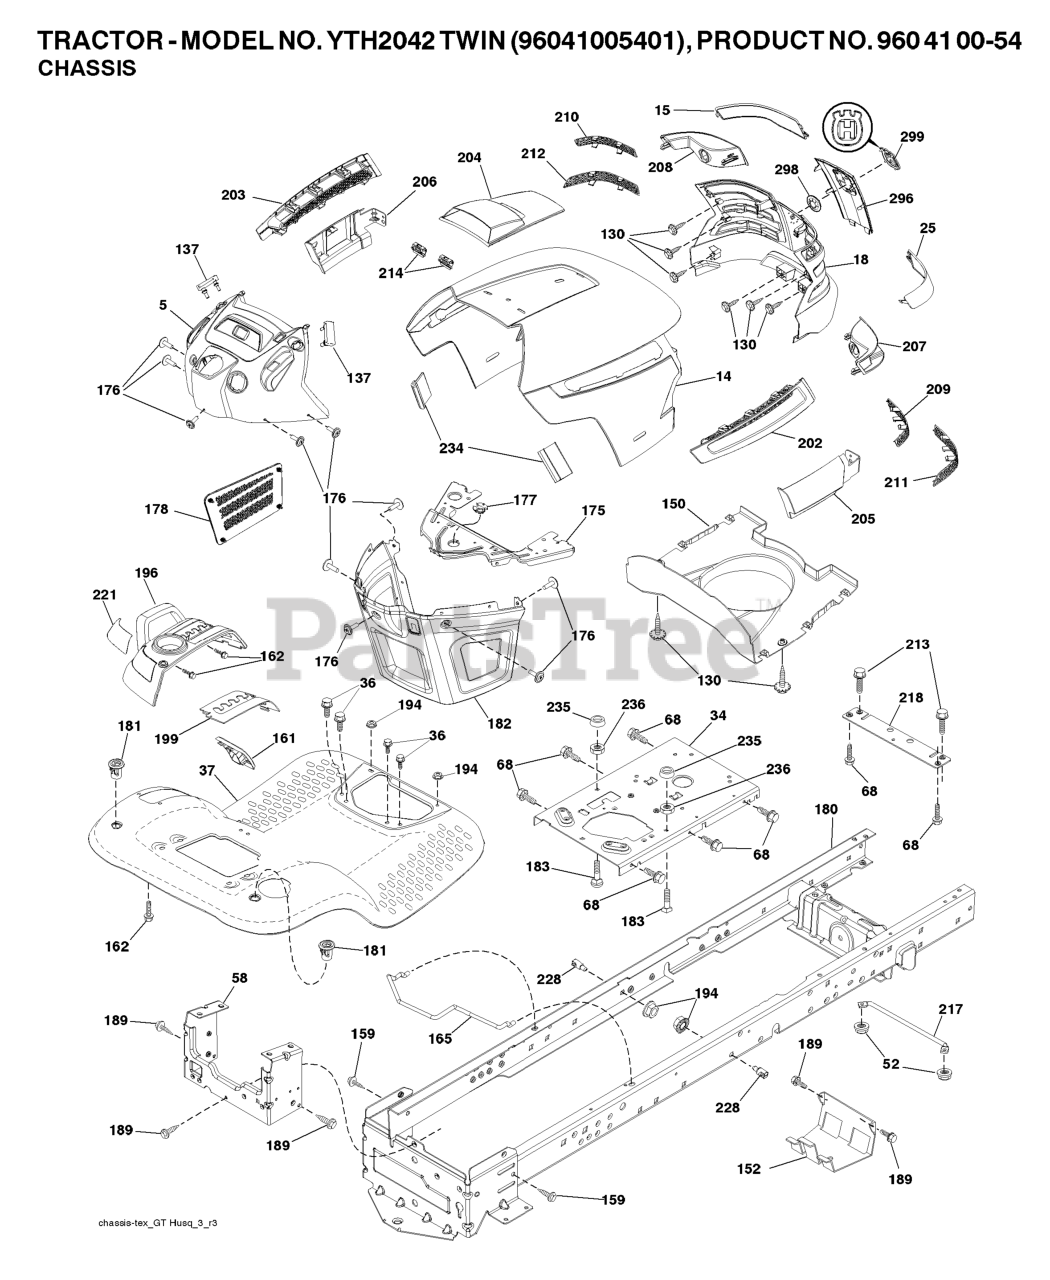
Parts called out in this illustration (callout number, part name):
5	DASH.ASM.HUSQ.GT.E.RECT.W/CK
14	HOOD
15	LENS.LH.TEX.GT.HUSQ.CL
18	GRILL.ASM.HUSQ.TG/CRD.W/TRIM
25	LENS.RH.TEX.GT.HUSQ.CL
34	PLATE.ENGINE.WELDED.CHASSIS
36	SCREW 5/16"
37	FENDER.PNT.TX.GT.CH/FW.ORANGE
52	LOCKNUT
58	DRAWBAR.UPPER.2PC,LRG.FENDER
68	Screw 5/16-18 x 1/2 Hex, Self Tapping 5/16-18 x 1/2
130	SCREW.#10 X 0.750.BOS
137	BUMPER DASH
150	AIR.DUCT.HOOD.TEX.GT.HUSQ
152	SHIELD.BROWNING.W/TEX
159	SCREW, 3/8-16X3/4
161	CONSOLE.FUEL.WINDOW.HU
162	SCREW.HI-LO.CONSOLE
165	SUPPORT.TANK.REAR.W/TEX
175	PLATE.CROSSMEMBER.HUSQ
176	SCREW.#10-24X5/8.RN.QU
177	BUSHING, STEERING
178	CARGO.ASM.NET.TXGT.W/C
180	CHASS.WLDMNT.TLT.12GA/2PC.20"
181	BUSHING.MNT.FEND.CRGO.
182	DASH.LOWER.COMMON.12V.ADAPTOR
183	BOLT.5/16-18X1-1/4 FULL.THREAD
189	SCREW
194	NUT LOCK HEX FLANGE 5/16-18
196	RP CONSOLE.ASM.DECKLFT.W/
199	PLATE.DECK.LIFT.HUSQVARNA.GT
202	VENT.SIDE.HOOD.HUSQ.RH.GREY
203	VENT.SIDE.HOOD.HUSQ.LH.GRAY
204	HOOD VENT
205	SKIRT.HOOD.SIDE.HUSQ.RH.GREY
206	SKIRT.HOOD.SIDE.HUSQ.LH.GREY
207	BEZEL.RH.TEX.GT.HUSQ
208	BEZEL.LH.TEX.GT.HUSQ
209	INSERT.HEX.GRILL.HUSQ.GREY
210	INSERT.HEX.GRILL.HUSQ.
211	INSERT.HEX.GRILL.HUSQ.
212	INSERT.HEX.GRILL.HUSQ.
213	BOLT
214	CLIP.RETAINER.TINNER.
217	ROD.PIVOT.HOOD
218	X-PIECE.HOOD.STOP.NON/
221	REFLECTOR.LH.TEX GT HU
228	STUD.FASTNER.W/ANTI-ROTATE
234	BUMPER.HOOD.TEX.HUSQVARNA
235	SPACER FENDER
236	NUT.CENTERLOCK.5/16-
238	TRIM.HUSQ.TG/CRD.SERVICE
298	NUT PUSH M
299	RP LOGO
